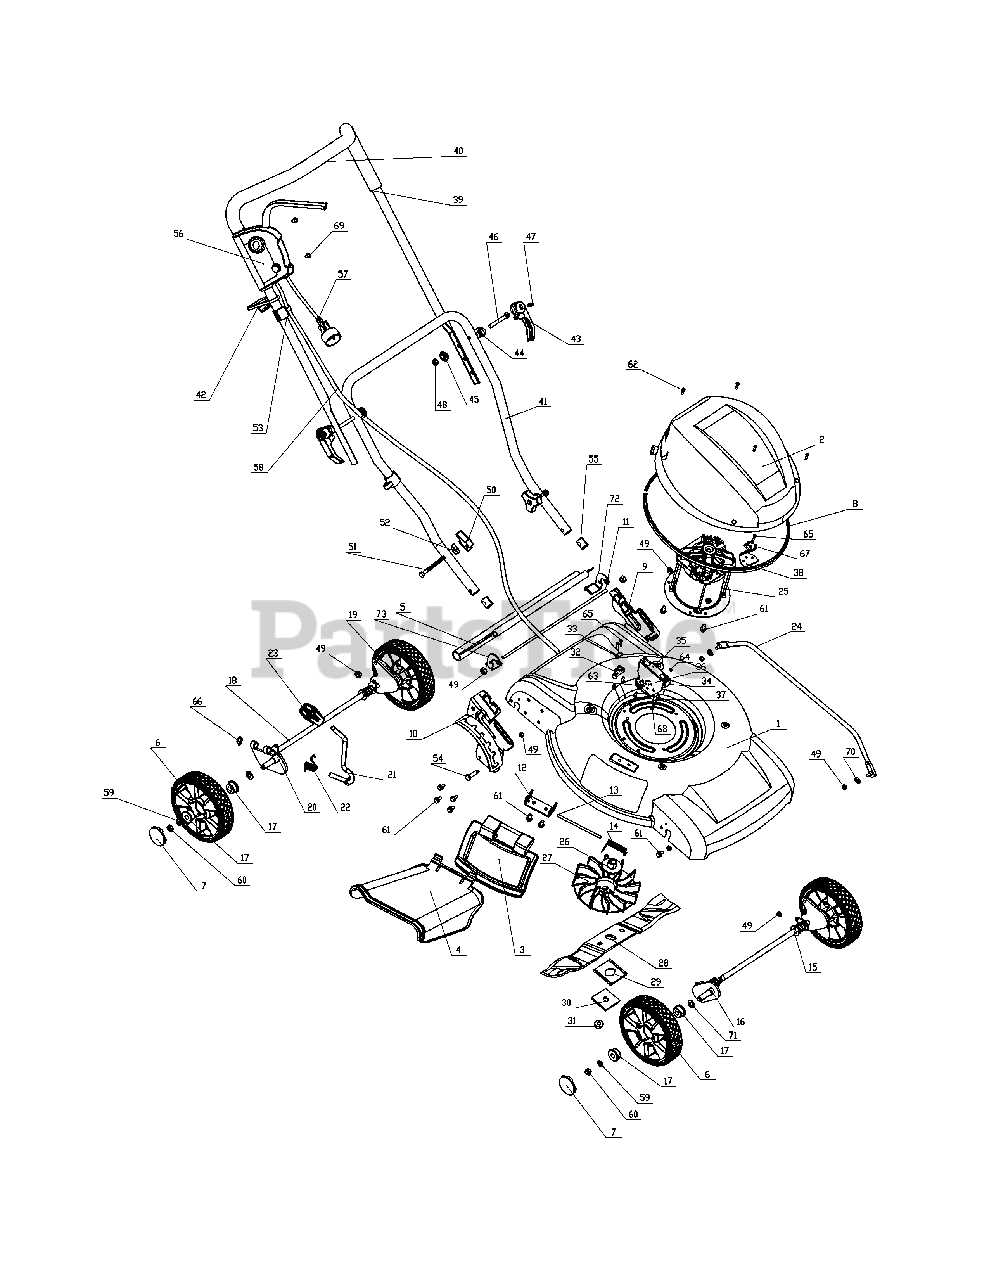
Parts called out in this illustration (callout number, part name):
1	Deck, 19", 3-In-1
2	Shroud
3	Door, Discharge
4	Chute, Discharge
5	Trailshield
6	Wheel, Front
7	Cap, Wheel
8	Seal, Shroud
9	Bracket, Wheel, Left
10	Bracket, Wheel, Right
11	Rod, Trailshield
12	Bracket, Defl ector, Chute
13	Rod, Door, Chute
14	Spring, Door, Discharge
15	Axle, Assembly, Front
16	Washer
17	Bush, Wheel
18	Axle, Assembly, Rear
19	Washer
20	Washer
21	Lever, Spring
22	Spring, Lever
23	Knob, Adjustment, Height
24	Link, Height, Adjustment
25	Motor
26	Adapter, Blade
27	Fan, Electric
28	Blade, 19", 2-in-1
29	Washer
30	Washer
31	Nut, M10 x 1.25
32	Support, Cord
33	Keeper, Cord
34	Resistor
35	Resistor, Holder
36	Resistor, Bracket
37	Heat Sink, Resistor
38	Base, Electric-Bridge
39	Handle, Upper
40	Sleeve, Handle, Upper
41	Handle, Lower
42	Retainer, Cord
43	Knob, Trigger
44	Washer
46	Pin, Cotter
47	Pin, Spring
48	Nut, M8
49	Nut, M6
51	Screw, M8
52	Washer, Curve
53	Holder, Cord
55	Cap, Handle
56	Switch Box Assembly
58	Cord, Switch
59	Washer, Flap, 8mm
60	Nut, M8
61	Screw, M6 X 12
62	Screw, M5x12
63	Screw, M4 X 16
64	Nut, Lock, M4
65	Screw, St 4.2 X 16
66	Ring, Snap
67	Electrical, Bridge
68	Screw, St, 4.8 X 16
69	Screw, St, M4.2 X 25
70	Pin, Cotter
71	Washer, Spring
72	Bracket, Trailshield, Left
73	Bracket, Trailshield, Right
